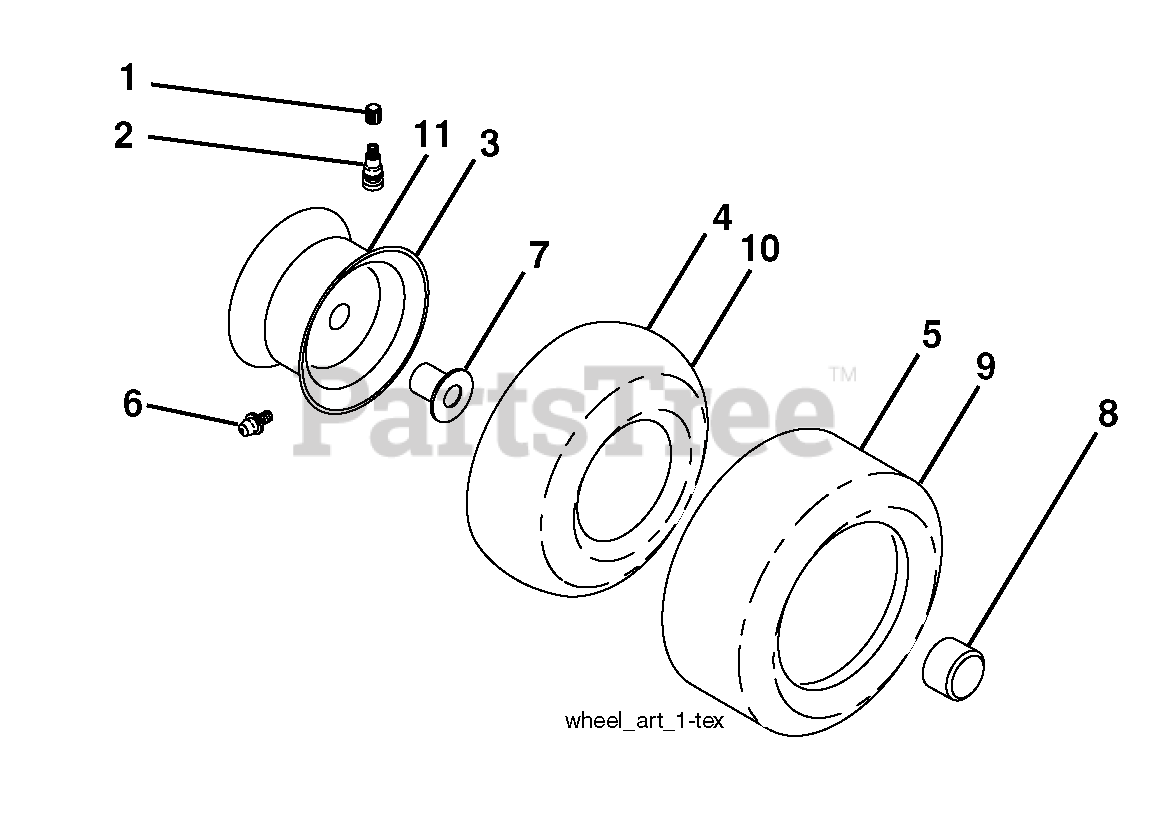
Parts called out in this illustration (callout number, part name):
1	Cap Valve Tire
2	Stem Valve
3	Rim Asm 6" Front
4	Tube Front
5	Tire Front 15 x 6.0-6
6	Fitting Grease
7	Bearing Flange
8	Cap Axle Blk 1 50 x 1 00
9	Tire Rear 18 x 9.5-8 "Turf Saver LT"
10	Tube Rear
11	Rim Asm 8" Rear
